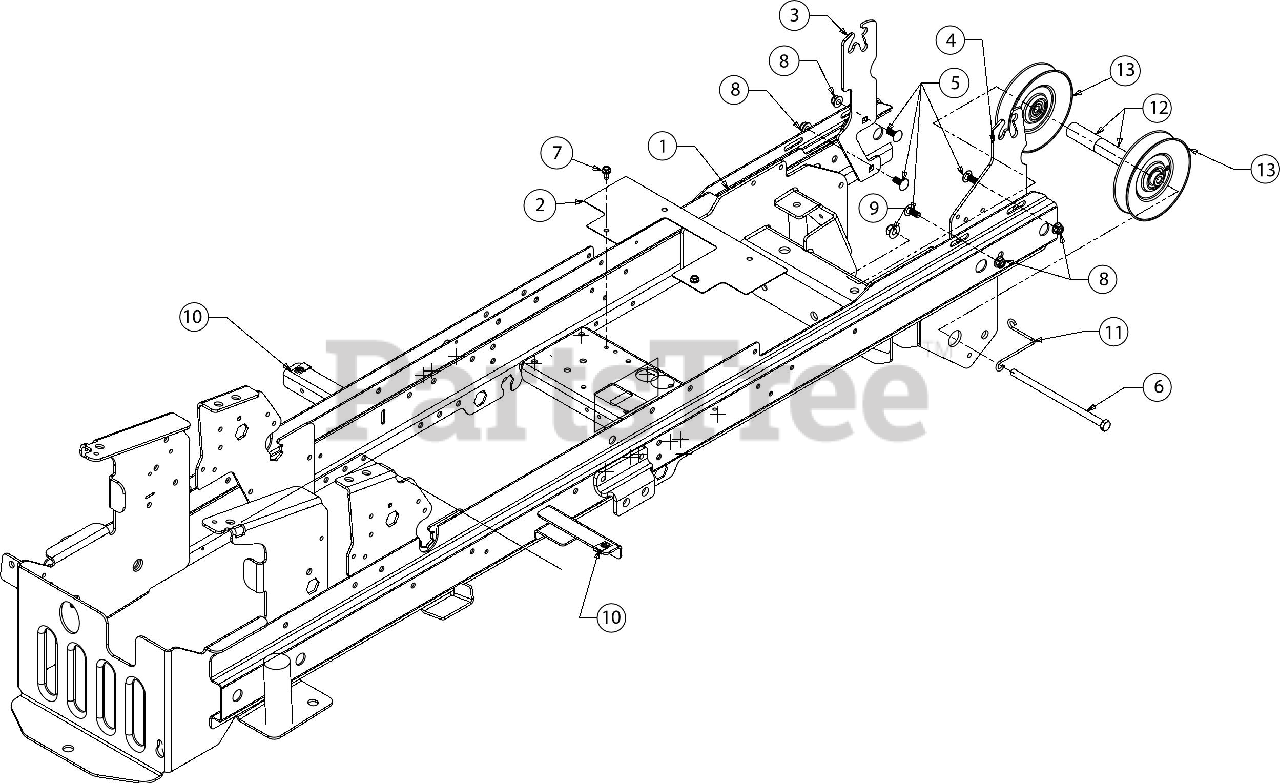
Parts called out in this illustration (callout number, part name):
1	MANUAL LIFT FRAME ASSEMBLY
3	HOOD PIVOT BRACKET (LH)
4	HOOD TILT BRACKET
5	CARRIAGE BOLT 5/16-18 x .75
6	SCREW 3/8-16 x 7.25 GR5
7	SCREW 1/4-20 X.500
8	FLANGE LOCK NUT 5/16-18
10	U-NUT
11	BELT GUIDE
12	SPACER .41 x .875 x 2.19
13	IDLER PULLEY 5.06
